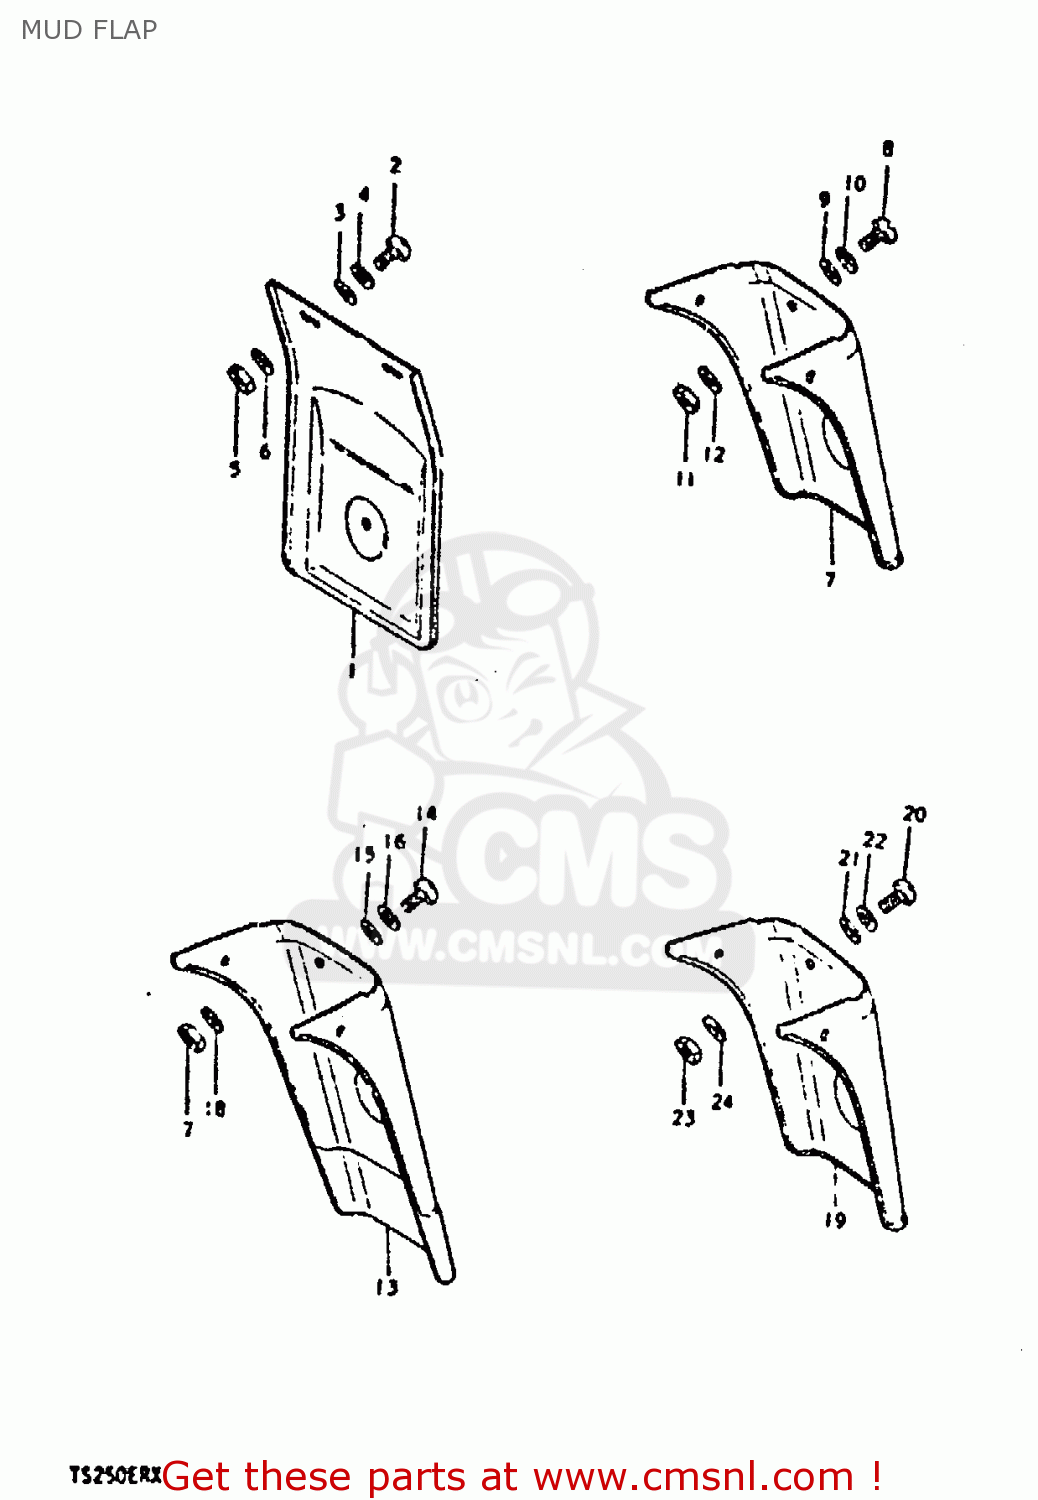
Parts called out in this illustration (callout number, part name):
1	FLAP,RR FENDER MUD
2	SCREW
3	WASHER
4	LOCK WASHER
5	NUT
6	BOLT
